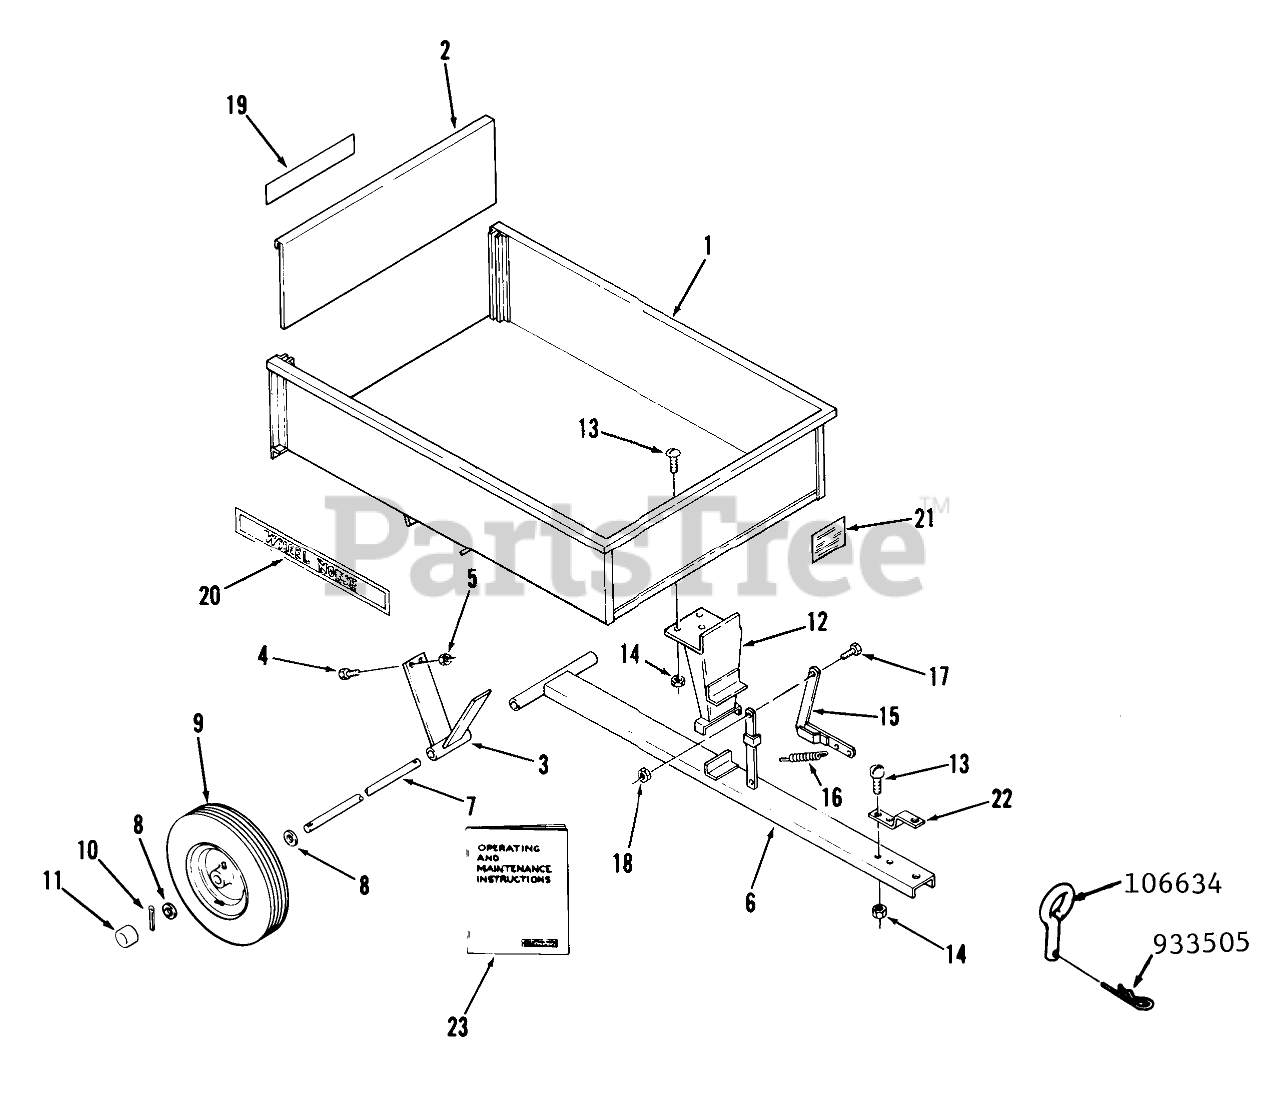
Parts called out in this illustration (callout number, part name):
1	Bed Assembly
2	Rear Gate
3	Axle Holder Assembly
4	BOLT
5	Nut
6	Drawbar Assembly
8	Special Washer
9	Wheel Assembly (4.30-8)
11	HUB CAP
12	Drawbar Spacer Assembly
13	Truss Hd. Bolt 3/8-16 x 3/4
14	Nut
15	Latch Assembly
16	SPRING
17	Bolt
18	Nut
19	DECAL-WHEEL HORSE
20	Decal
21	Decal-Weight Limit
22	Clevis
23	Operating and Maintenance Instructions
23	Wheel
23	Wheel Bearing
